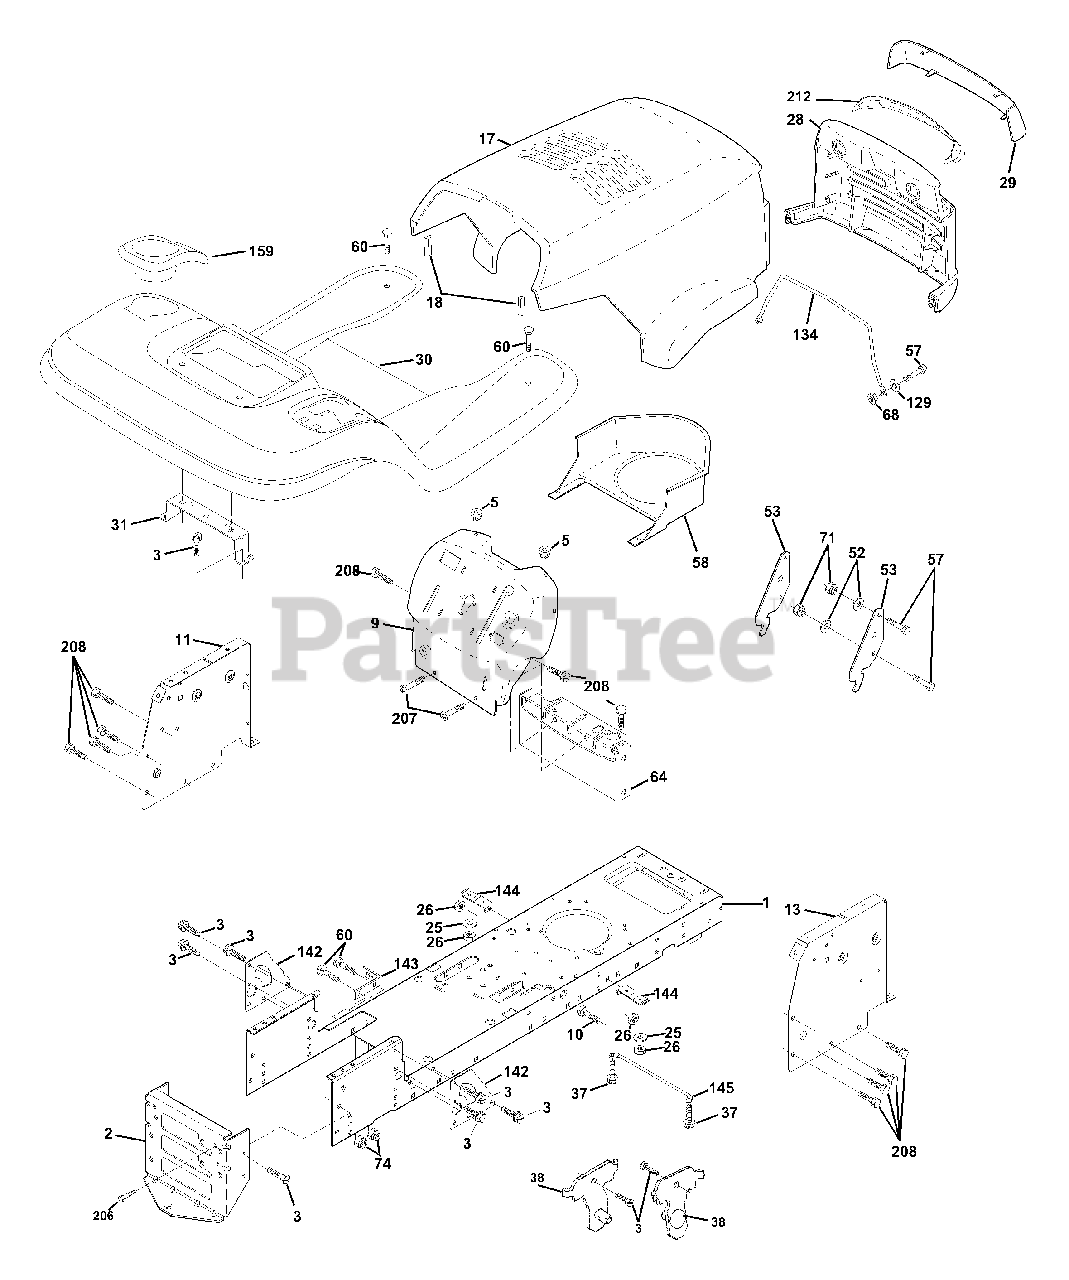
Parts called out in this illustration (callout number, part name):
1	Chassis Stamping
2	Drawbar, 12 Ga.
3	Screw 3/8-16 x 3/4
5	Bumper Hood/Dash
9	Dash Slkscr
10	Bolt Carriage 3/8-16 x 1
11	Panel Dash Lh
13	Panel Dash Rh
17	Hood LT/PL Husqvarna
18	Bumper Hood
25	Washer 13/32 X 13/16 X 12 Ga
26	Nut Lock Hex W/Ins 3/8-16 Unc
28	Grille LT/PL Husqvarna
29	Lens LT/PL Husqvarna
30	Fender Footrest STLT Pnt
31	Bracket Support Fender
37	Screw Thdrol 6/16-18 x 1/2 TYT
38	Bracket Asm Pivot Mower Rear
52	Washer 9/32 x 7/8 x 16 Ga.
53	Bracket Pnt. Pick off LT/PL Husqvarna
57	Bolt Hex 1/4-20 x 3/4
58	Air Duct Engine P/L
60	Bolt Rdhd Sqnk 3/8-16unc x 3/4
64	Dash Lower STLT
68	Nut Keps Hex 1/4-20unc
71	Nut Cronwn Lock 1/4-20 Unc Blk D
74	Nut Crownlock 3/8-16 UNC
129	Washer 9/32 x 5/8 x 16 Ga.
134	Rod Support Hood LT/PL Husq.
142	Plate Reinforcement STLT
143	Bracket Swaybar Chassis
144	Bracket Pnt Footrest STLT
145	Rod Pivot Chassis/Hood
159	Cupholder Stlt Grey
206	Bolt Shoulder 5/16-18 TT
207	Screw Thdrol 5/16-18 x 1/2
208	Screw Thdrol 3/8-16x1/2 Ty-tt
212	Insert Lens Reflective
